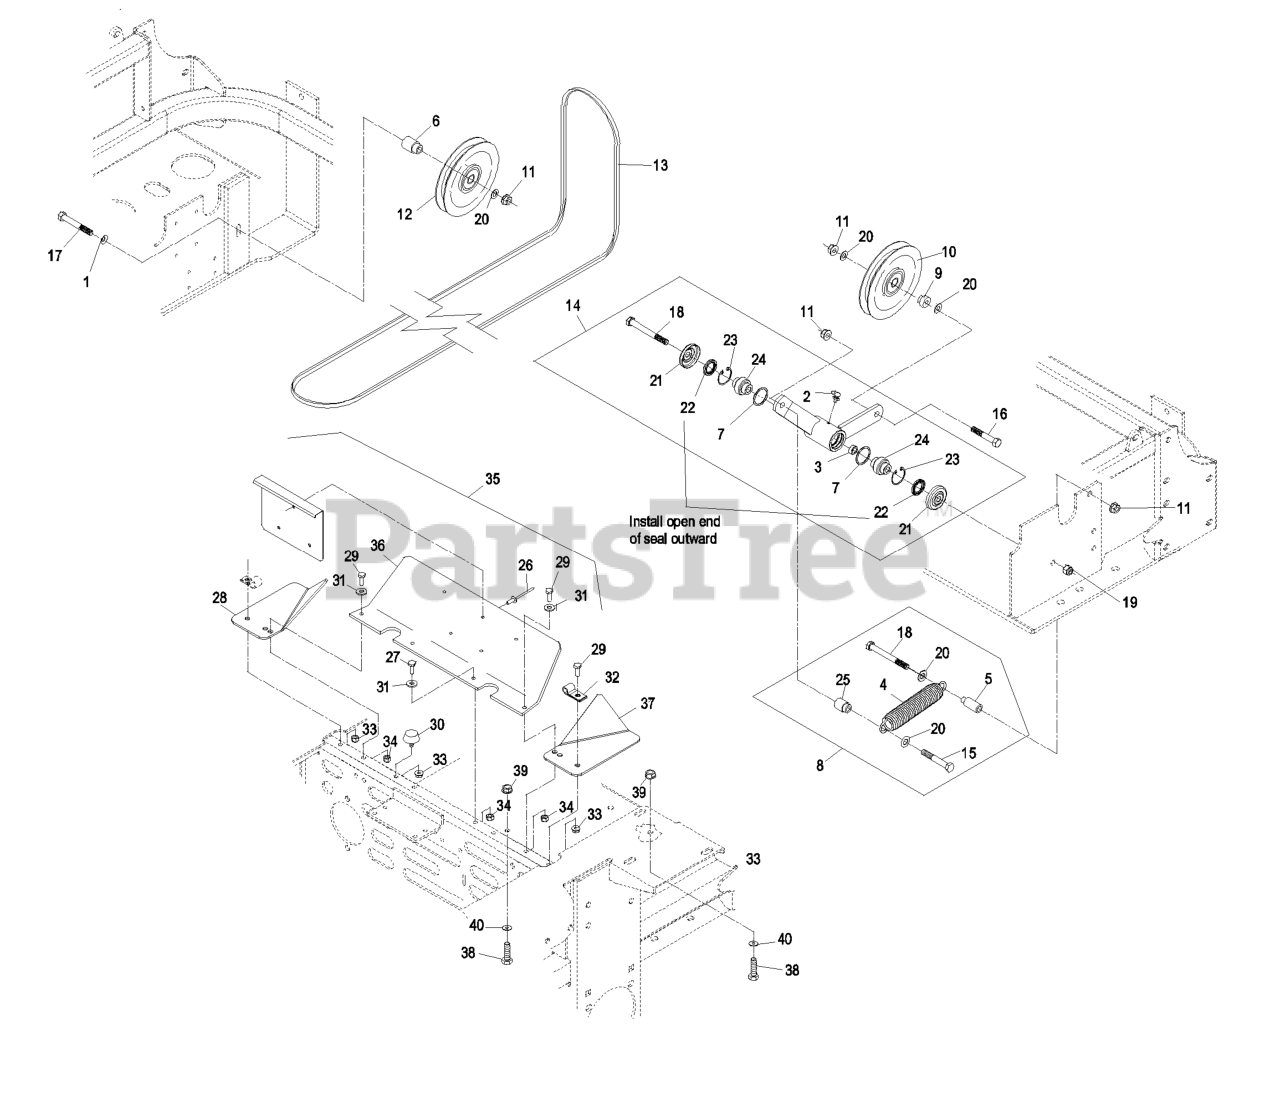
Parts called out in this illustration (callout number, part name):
1	WASHER-BELLEVILLE
2	FITTING-GREASE, 90 DEG
5	SPACER,SPRING MOUNT
6	BUSHING-IDLER
8	KIT,MULE DRIVE SPRING
9	BUSHING-IDLER
10	PULLEY-IDLER
11	NUT-HHF, WHIZ
12	PULLEY-IDLER
13	BELT,B 116.1"
14	KIT,MULE IDLER LZ
15	SCREW-HH
16	SCREW-HH
17	SCREW-HH
18	SCREW-HH
19	NUT-LOCK, NI
20	WASHER-FLAT
21	GUARD-TOP
22	SEAL-LIP, SINGLE
23	RING-SNAP
24	BEARING-SPHERICAL
25	BUSHING-IDLER
26	RIVET-POP
27	SCREW-HH
28	SUPPORT-FRONT COVER, RH
29	SCREW-HH
30	BUMPER-RUBBER
31	WASHER-FLAT
32	CLIP-LOOM
34	NUT-LOCK, NI
35	SHIELD ASM
36	SHIELD-ENGINE
37	SUPPORT-FRONT COVER, LH
38	SCREW-HH
39	NUT-HHF, WHIZ
40	WASHER-BELLEVILLE
